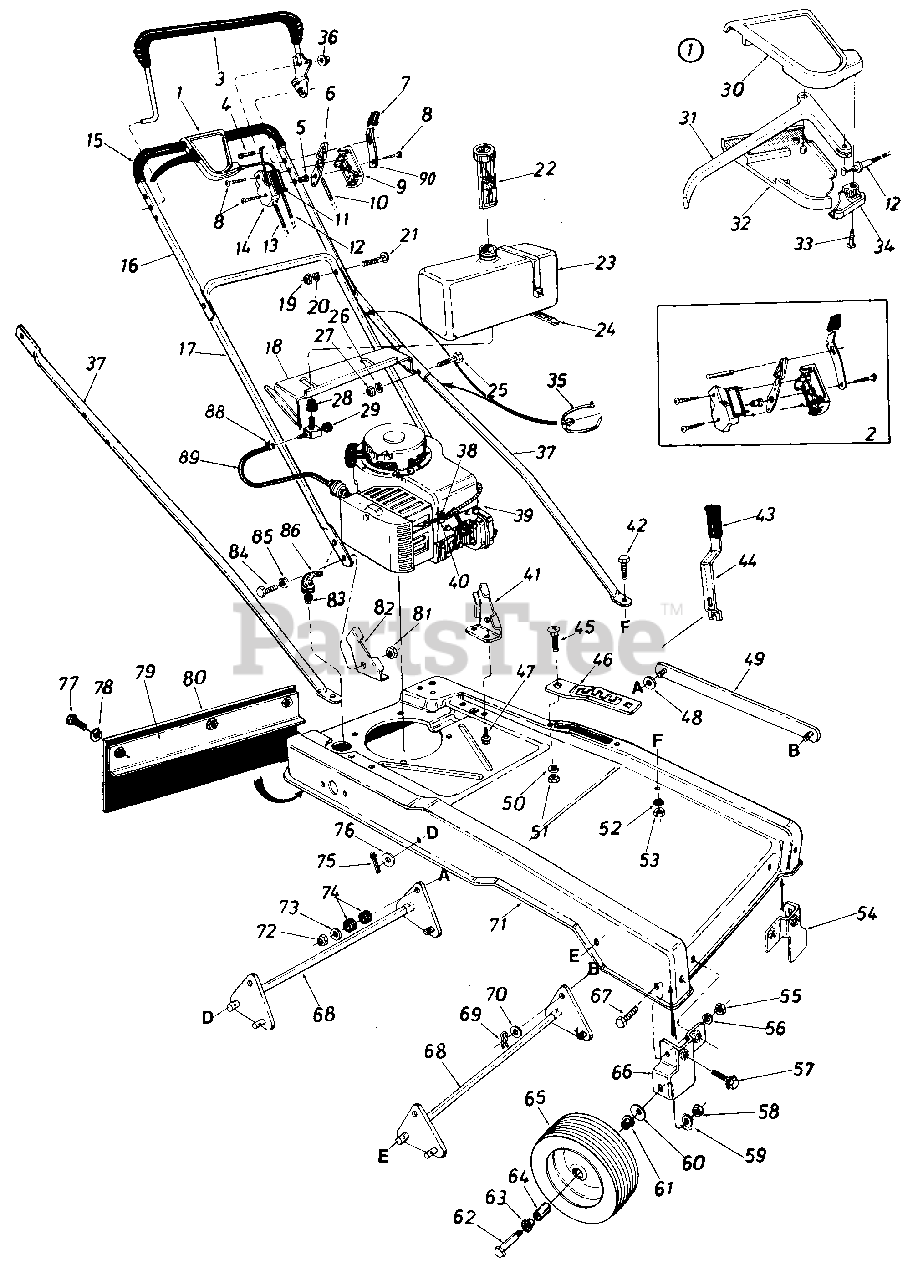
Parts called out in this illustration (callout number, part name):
1	Clutch Control Housing Comp.
2	Control Housing Comp.
3	Control Handle Ass'y.
4	Lock Pin
5	Control Disc Pin
6	Throttle Control Lever
7	Spring Lever Knob
8	Truss Mach. Hi-B Tap Scr. #12 x 1.50" Lg.
9	Control Panel Half
10	Throttle Control Wire 43" Lg.
11	Control Label-Throttle
12	Self-Propelled Cable 50" Lg.
13	Drive Clutch Cable-46" Lg.
14	Clutch Panel Half
15	Grip 22" Lg.
16	Upper Handle (Painted)
17	Lower Handle (Painted)
18	Gas Tank Mounting Brkt.
19	Hex Nut 5/16-18 Thd.
20	L-Wash. 5/16" I.D.
21	Carriage Bolt 5/16-18 x 1.50" Lg.*
22	Gas Gauge 1-3/4-6 x 5.50" Lg.
23	Gas Tank
24	Cable Tie 30.6" Lg.
25	Hex Bolt 5/16-24 x 1.25" Lg.*
26	L-Wash. 5/16" I.D.
27	Hex Nut 5/16-24 Thd.
28	Bushing-Gas Tank
29	Fuel Shut-Off Valve w/Screen
30	Control Cover Half-Upper
31	Control Lever
32	Control Cover Half-Lower
33	Flat "C" Sunk Hd. Tap Scr. #10 x .75" Lg.
34	Cable Mounting Cap
35	Cable Tie
36	Push Cap
37	Strut .75" O.D. x 43.44" Lg.
38	Hex Sems Scr. #10-32 x .62" Lg.
39	Engine-5 H.P.
40	Casing Clamp
41	Handle Mount Brkt.-L.H.
42	Hex Bolt 5/16-18 x .75" Lg.
43	Grip-Black
44	Lift Handle
45	Carriage Bolt 5/16-18 x .62" Lg.
46	Lift Handle Support Brkt.
47	Hex Wash. Hd. B-Tap Scr. 5/16-1 8 x .50
48	Fl-Wash. .406" I.D. x 1.25" O.D.
49	Connecting Link Ass'y.
50	L-Wash. 5/16" I.D.
51	Hex Nut 5/16-18 Thd.
52	L-Wash. 5/16" I.D.
53	Hex Nut 5/16-18 Thd.
54	Wheel Brkt. Ass'y.-L.H.
55	Hex Nut 5/16-18 Thd.
56	L-Wash. 5/16" I.D.
57	Hex Sems Bolt 5/16-18 x .75" Lg.
58	Hex Cent. L-Nut 3/8-16 Thd.
59	L-Wash. 3/8" I.D.
60	Bell-Wash. .400" I.D. x .88" O.D.
61	Flanged Ball Brg. 3/8" I.D.
62	Hex Bolt 3/8-16 x 2.00" Lg.
63	Flanged Ball Brg. .501" I.D.
64	Spacer .375" I.D. x .505" O.D. x 1" Lg.
66	Wheel Brkt. Ass'y.-R.H.
67	Hex Sems Bolt 5/16-18 x .75" Lg.
68	Lift Brkt. Shaft Ass'y.
69	Intern. Cotter Pin 5/16" Dia.
70	Fl-Wash. .385" I.D. x .88"
71	Hi-Wheel Frame
72	Hex Ins. L-Nut 3/8-24 Thd.
73	Fl-Wash. .385" I.D. x .88"
74	Rubber Wash. .33" I.D. x .87" O.D.
75	Cotter Pin 1/8" Dia. x 1" Lg.*
76	Fl-Wash. .51" I.D. x 1.0"
77	Hex Bolt 1/4-20 x .62" Lg.
78	L-Wash. 1/4" I.D.
79	Retaining Strip Ass'y. 3" x 15" Lg.
80	Rear Flap 7.5 x 20" Lg.
81	Hex Nut 3/8-16 Thd.
82	Handle Mount Brkt.-R.H.
83	Part of Engine
84	Hex Bolt 3/8-16 x .75" Lg.*
85	L-Wash. 3/8" I.D.
86	90 Deg. Elbow Male to Female 3/8
88	Hose Clamp-.406" Dia.
89	Fuel Line 15" Lg.
90	Lockout Lever
